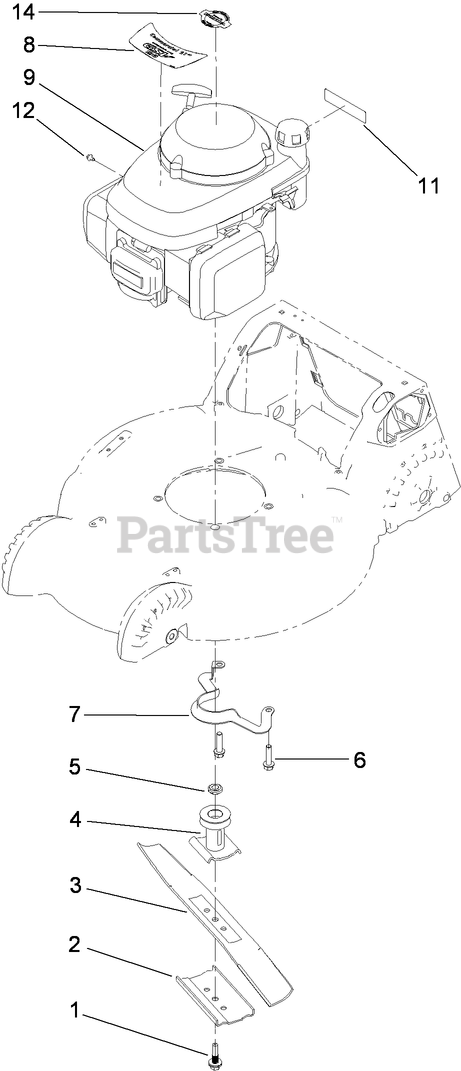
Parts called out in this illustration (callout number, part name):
1	BOLT-BLADE
2	SUPPORT-BLADE
3	BLADE-BAGGING
4	DRIVER-BLADE
5	Spacer-Driver
6	SCREW-HWH
7	GUIDE-BELT
8	DECAL-ENGINE
11	DECAL-ARRESTER, SPARK
12	SCREW-HWH
14	DECAL-ENGINE
